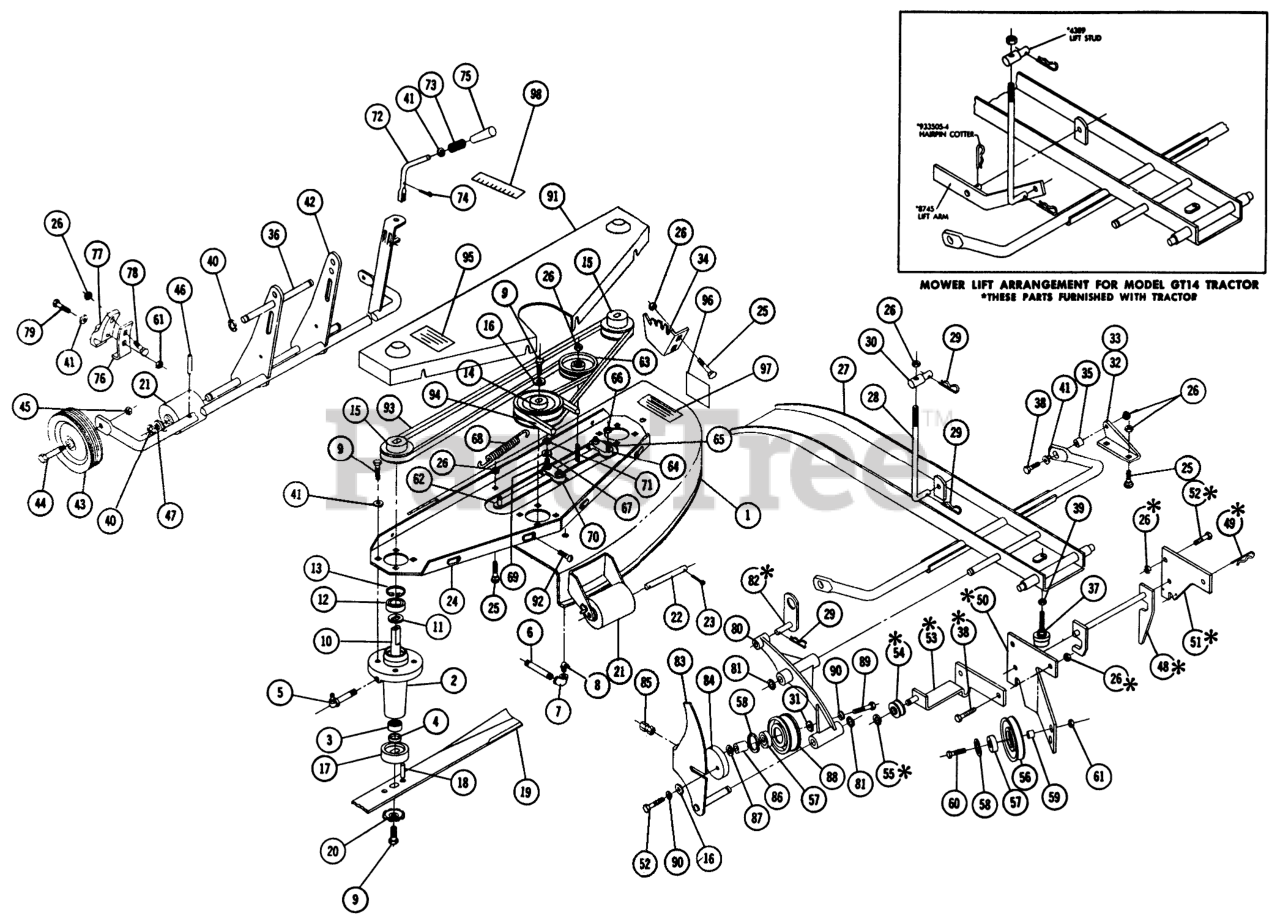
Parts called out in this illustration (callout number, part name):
1	Deck
2	Housing-Spindle
3	NEEDLE BEARING
4	SEAL-OIL
5	Fitting-Grease
6	Nipple 1/8 Pipe x 1" Long
7	ELBOW
8	Fitting-Grease 90deg.
9	Bolt 3/8-16 x 7/8
10	Shaft Spindle
11	WASHER
12	Ball
13	INT SNAP RING
14	Pulley-Center
15	Pulley-Right & Left
16	WASHER
17	Cup-Spindle
18	SPIROL ROLL PIN
19	Blade 16"
20	WASHER
21	Roller
22	Shaft
23	Cotter Pin
24	Support
25	Bolt-3/8-16 x 3/4
26	3/8-16 E.S.
27	Ass-y Support-Mower
28	ROD LIFT
29	Hairpin
30	TRUNNION-LIFT
31	Lockwasher
32	Bracket-Deck R.H.
33	Bracket-Deck L.H.
34	Quadrant
35	SPACER
36	Pin
37	LEVELER MOWER
38	Bolt 3/8-16 x 1
39	Nut, 5/16-18
40	E Ring
41	Washer
42	Gage Wheel Support 5-1482 & 5-1483
42	Ass-y.-Gage Wheel Support
43	Wheel
44	BOLT-SHOULDER
45	3/8-16 Jam Nut
46	Roll Pin
47	Washer
48	ASSY LATCH & SHAF R
49	Hairpin
50	MOUNTING BRACKET R
51	PLATE-MTG BRKT LH R (NS)
52	Bolt 3/8-16 x 1
53	ASSY BRACKET AND R
54	ROLLER
55	Lock Rod
56	PULLEY IDLER
57	BEARING
58	INTERNAL SNAPRING
59	SPACER
60	Bolt, 3/8-16 x 1/2
62	ASSY BAR IDLER SUPPO
63	Pulley-Idler
64	Side Block
65	Bolt-5/16-18 x 1/4
66	Nut 5/16-18
67	Washer
68	SPRING R
69	Bolt-5/16-18 x 1 1/2
70	SLIDE
71	Nut-Nylok
72	FORK
73	Spring
74	Hairpin
75	GRIP
76	Clip-Axle
77	SUPPORT AXLE
78	Bolt Carriage 3/8-16 x 1
79	Bolt 3/8-16 x 1 5/8
80	ARM PIVOT R
81	RING LAM L 262
82	Cam Arm
83	ASSEMBLY CAM LEVE R
84	Ass-y Idle Support
85	Nut
86	SPACER
87	Lockwasher-3/8 Int.Tooth
88	PULLEY IDLER
89	Bolt Hex 3/8-16
90	Lockwasher
91	Cover
92	Bolt 1/4-20 x 3/8
93	V-BELT
94	V BELT
95	Decal Belt Installation
96	Decal
97	Decal
98	Decal-Height Adj.
